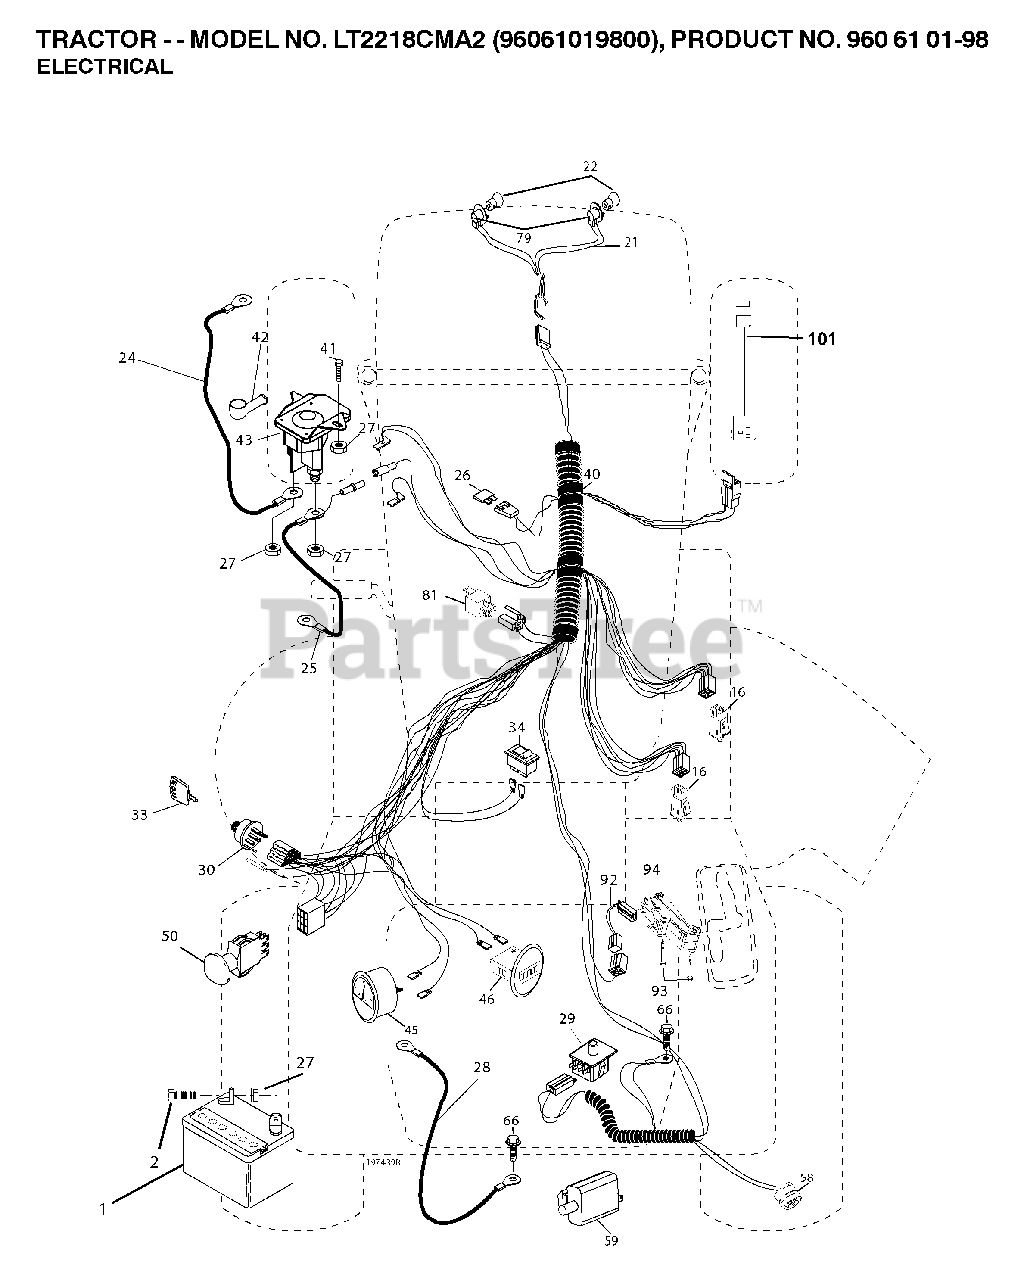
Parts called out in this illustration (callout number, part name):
1	BATTERY 12V .35 AMP
16	SWITCH INTERLOOK PUSH-IN
21	HARNESS.W/LIGHT SOCKET
22	LIGHTBULB
24	BATTERY CABLE GT
25	CABLE BATTERY
26	FUSE 20AMP
27	NUT
28	CABLE GROUND
29	SWITCH.SEAT.DP W/RAMPS
30	SWITCH.IGN.DELTA.W.LGH.ROS
33	KEY MLD GEN DELTA
34	SWITCH LT
42	TERMINAL COVER
43	SOLENOID.W/BRASS.PLUNG
46	HOURMETER SNAP-IN
50	PTO SWITCH
58	BUZZER
79	BULB HOLDER ASM.
81	RELAY.ASSY.T
92	HARNESS.PIGTAIL.CONSLE
93	SCREW.PLASTITE
94	MODULE.REVERSE.ROS
101	PIGTAIL.MATNLK.NEW.HAR
